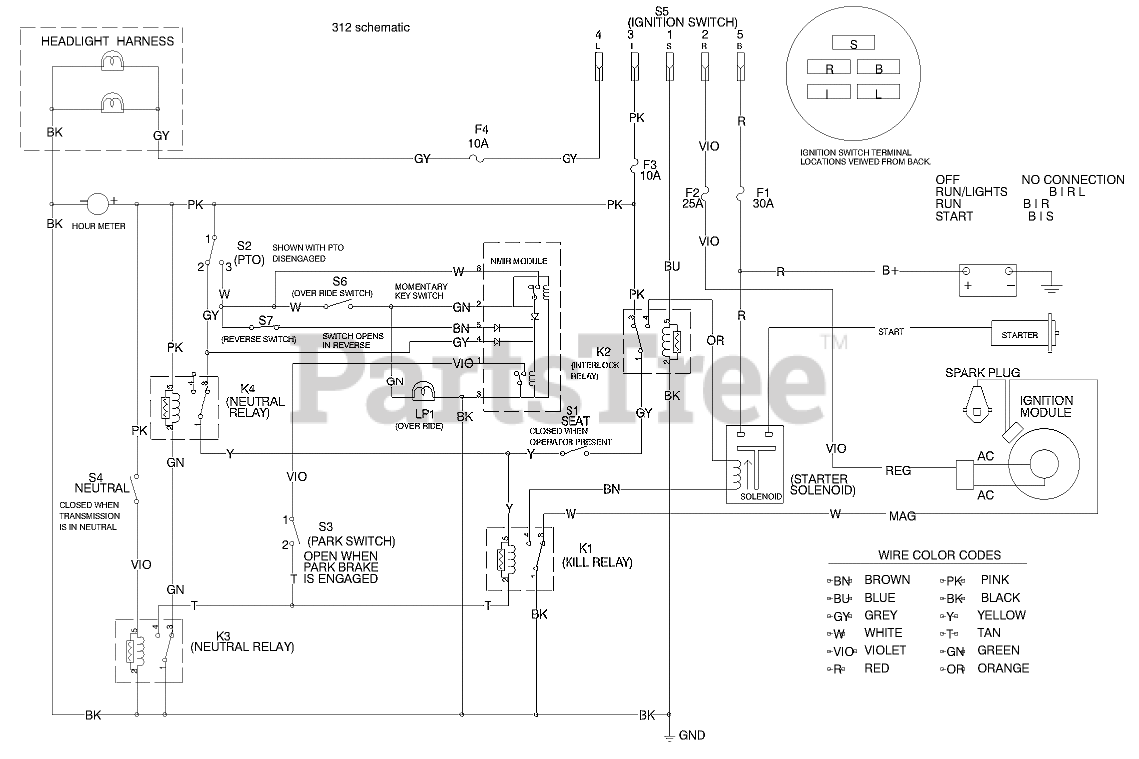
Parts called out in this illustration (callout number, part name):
F1	FUSE-30 AMP
F2	FUSE-BLADE, 25 AMP
F3	FUSE-10 AMP
F4	FUSE-10 AMP
